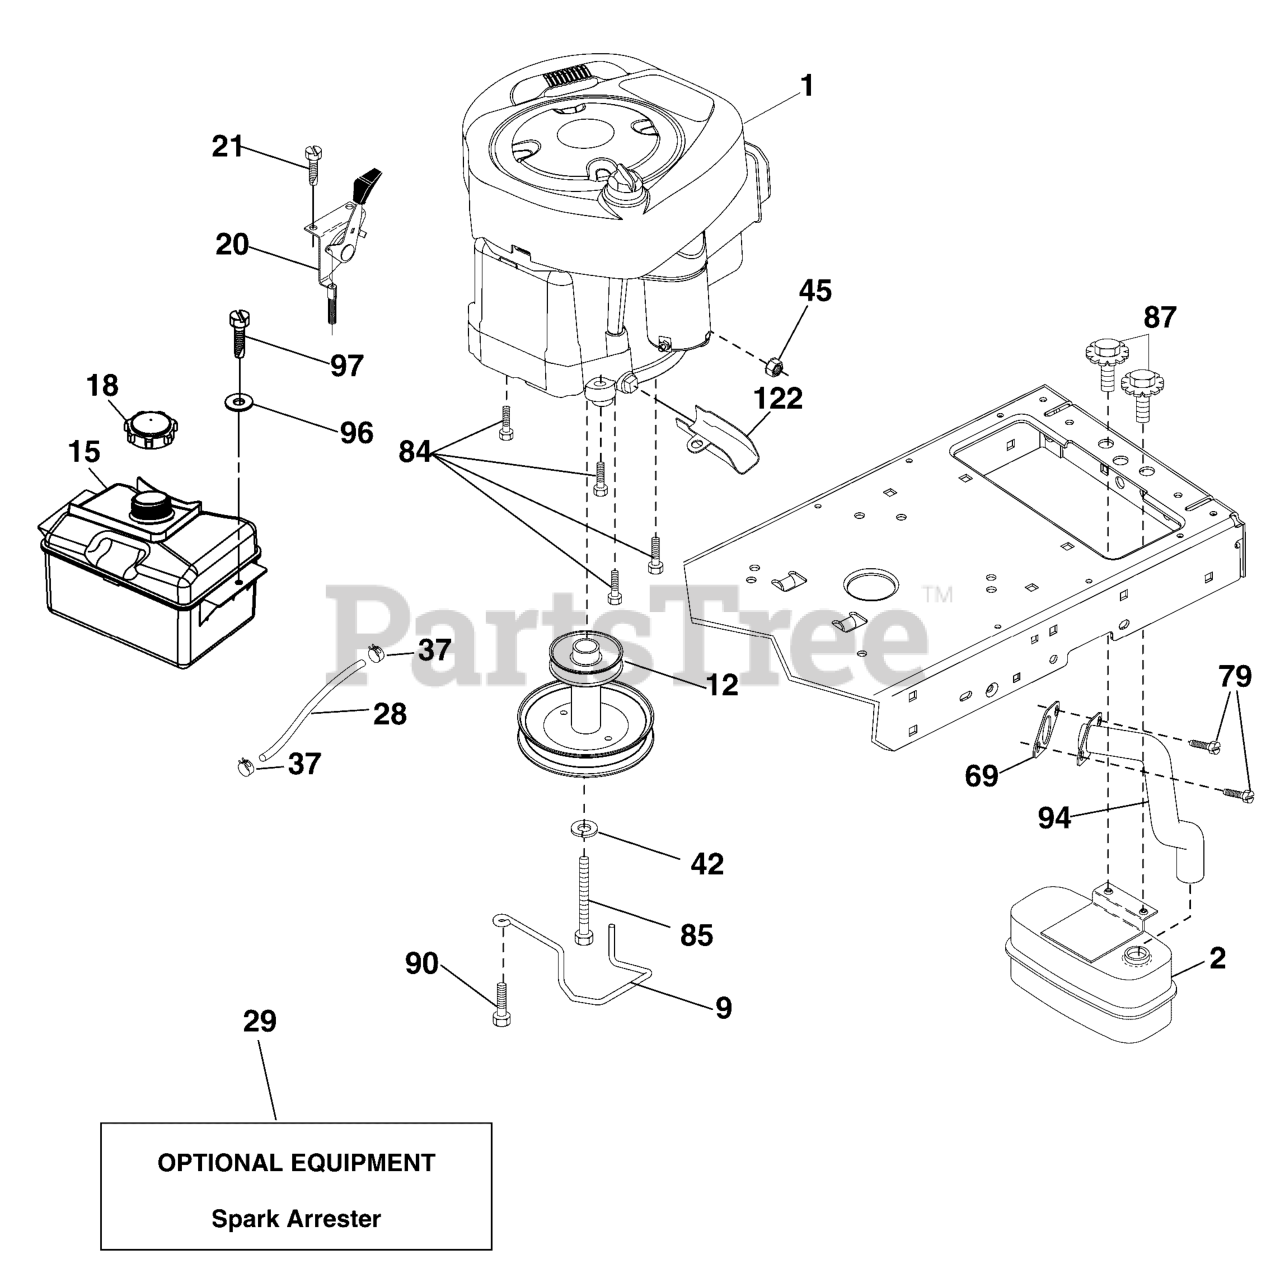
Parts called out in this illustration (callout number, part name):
1	*ENGINE, B&S Model No.
2	MUFFLER
9	KEEPER, Belt Engine
12	PULLEY, Engine
15	TANK, Fuel
18	CAP, Assembly Fuel
20	CONTROL, Throttle/Choke
21	SCREW, BOS Thread, 10 x .750
28	LINE, Fuel
29	KIT, Spark Arrester
37	CLAMP, Hose
42	WASHER, Lock, 7/16
45	NUT, Keps Hex 1/4-20 UNC
69	GASKET
79	SCREW, 5/16-18 x .75
84	SCREW, 3/8-16 x 1-1/4
85	BOLT, Hex, 7/16-20 x 4 x Gr. 5-1.5
87	BOLT, 5/16-18 UNC x 3/4
90	SCREW, 3/8-16 x 1.0
94	TUBE, Exhaust
96	WASHER, 9/32 x 7/8 x 16 Ga.
97	SCREW, 1/4-20 x 3/4
122	EXTENSION, Drain
